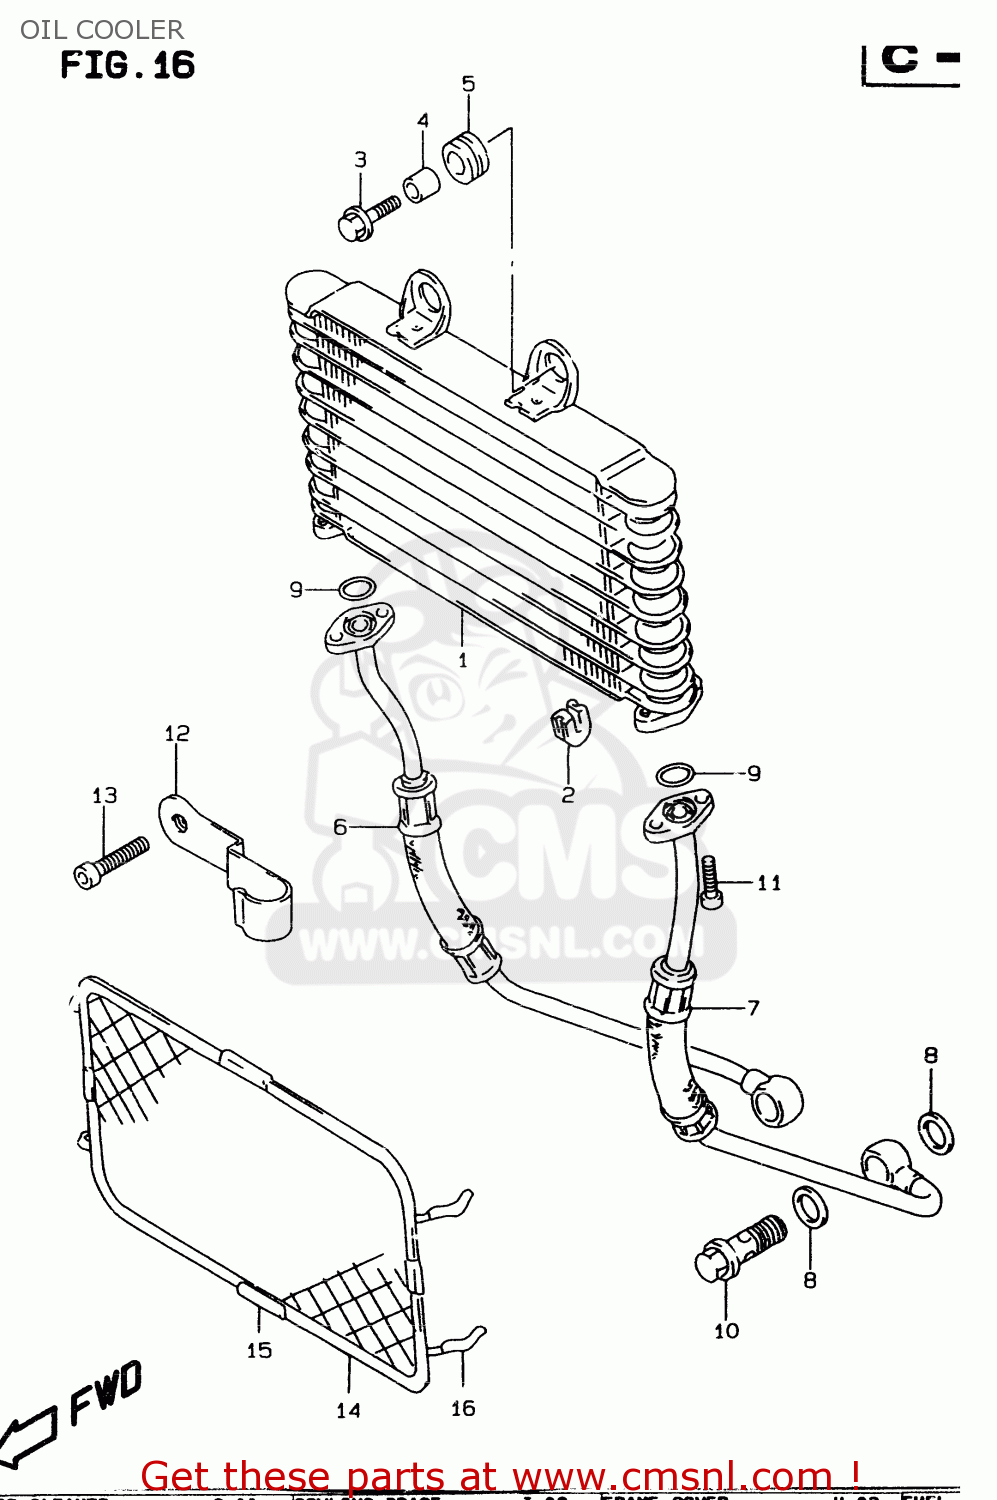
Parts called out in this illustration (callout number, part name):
1	COOLER ASSY,OIL
2	CUSHION,OIL COOLER NO.2
3	BOLT 6X20
4	SPACER(6.5X10X10)
5	CUSHION
6	HOSE,OIL COOLER,RIGHT
7	HOSE,OIL COOLER,LEFT
8	GASKET(16X22X2) (NAS)
9	O RING(D:2.4,ID:12.3)
10	BOLT UNION
11	BOLT,OIL FILLE
12	CLAMP,OIL HOSE
13	BOLT,STRANGER
14	GUARD COMP,OIL COOLER
15	PROTECTOR,CTR
16	HOSE(3X5X600)
